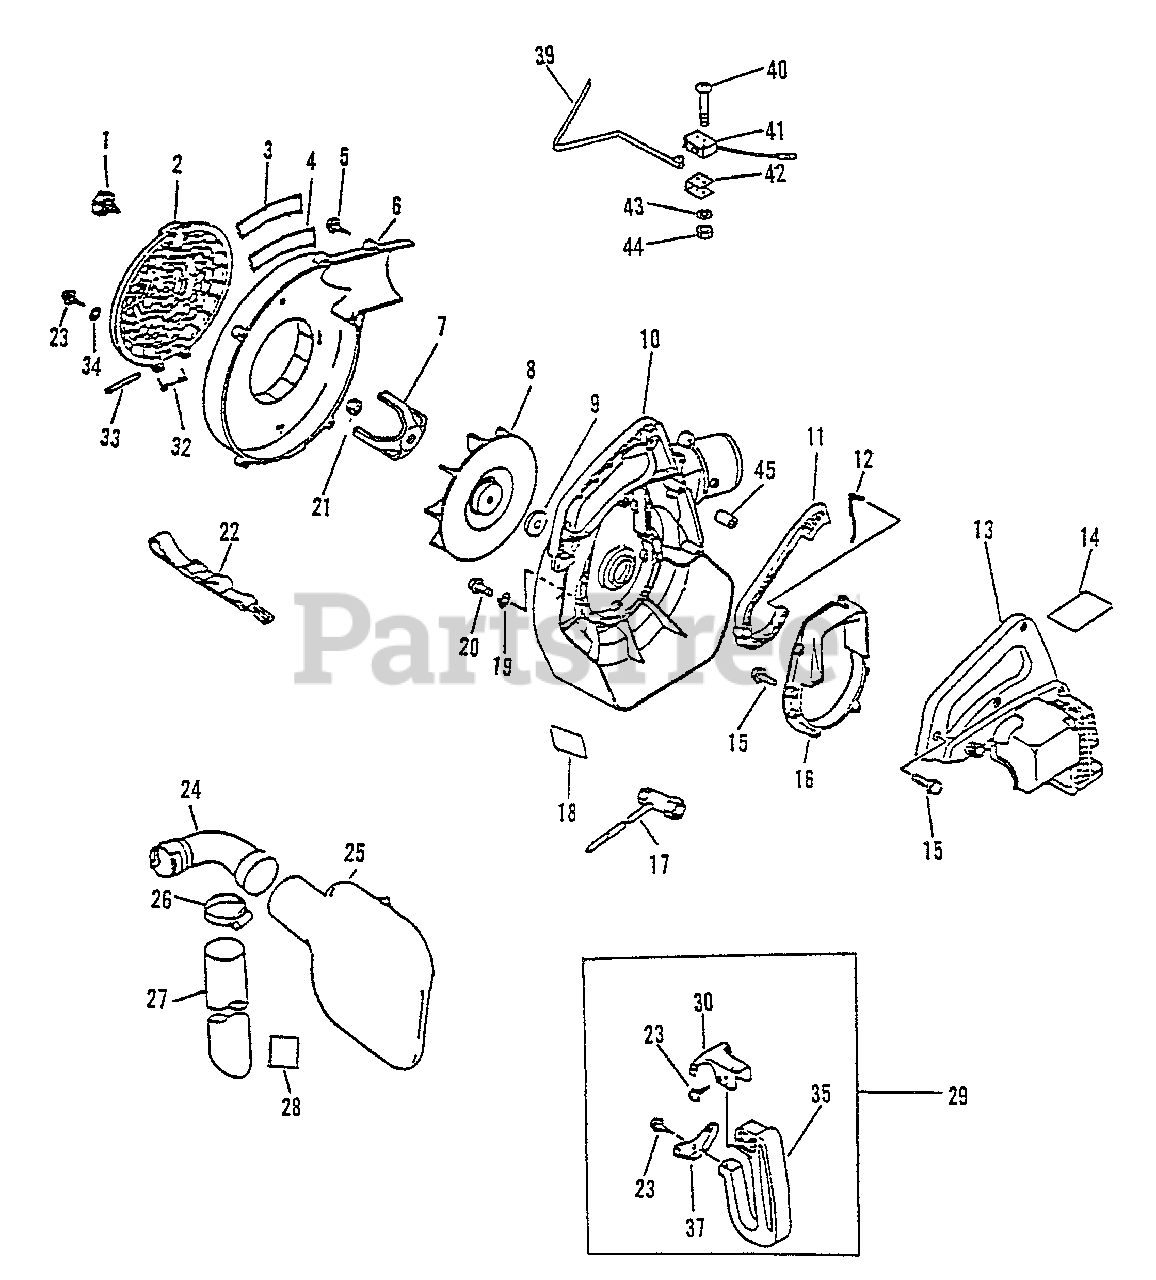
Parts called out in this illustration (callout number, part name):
1	THUMBSCREW
2	GUARD, DEBRIS
3	LABEL - SAFETY
4	LABEL - MODEL ES-1000
5	SCREW - 5X20 -- TAPPING
6	COVER, FAN - LEFT
7	BLADE, SHREDDER
8	FAN
9	WASHER - 8
10	COVER, FAN - RIGHT
11	TRIGGER, THROTTLE
12	ROD, THROTTLE
13	COVER, ENGINE
14	LABEL - HOT SURFACE
15	SCREW - 4X18
16	BRACKET, ENGINE
17	T-WRENCH - 13X19mm
18	LABEL - CAUTION
20	SCREW - 4X22
22	SHOULDER STRAP ASSY
23	SCREW - 5X14
24	TUBE, DEBRIS
25	BAG, DEBRIS
27	TUBE, VACUUM
28	LABEL - SHRED 'N' VAC
29	HANDLE ASSY - REAR
30	BRACKET, HANDLE - UPPER
35	HANDLE - REAR
37	BRACKET, HANDLE - LOWER
39	ACTUATOR
40	SCREW
41	IGNITION SWITCH ASSY
43	LOCKWASHER
45	TUBE, RETAINER
